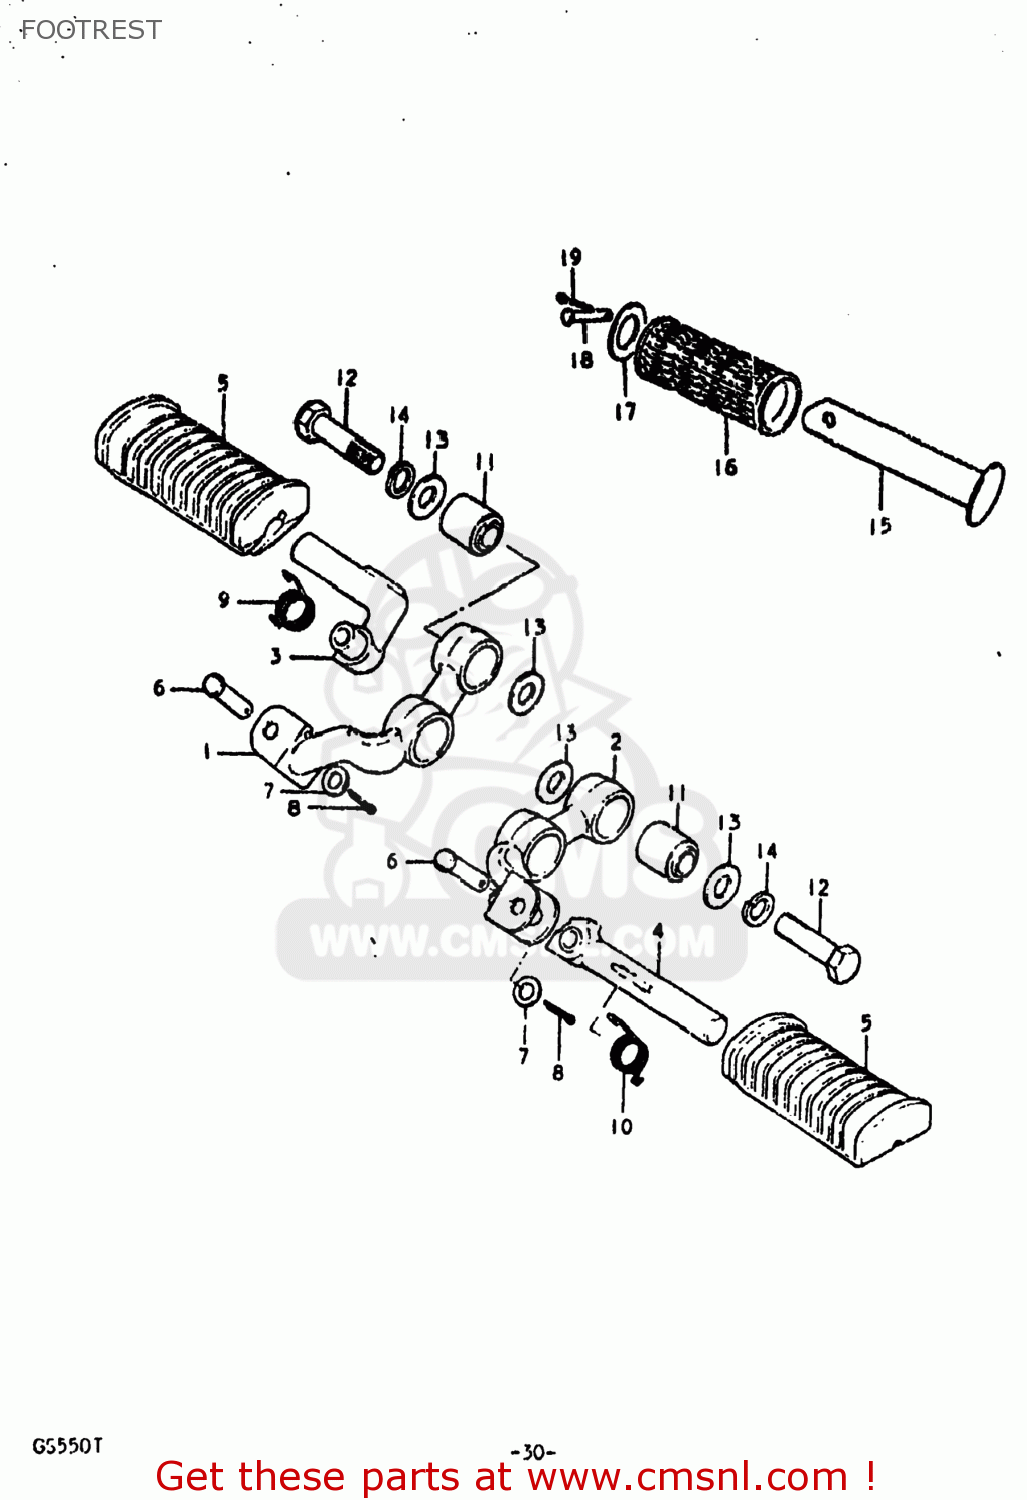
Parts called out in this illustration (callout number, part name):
1	BAR,FRONT FOOTREST,RIGHT
2	BAR,FRONT FOOTREST,LEFT
3	BAR,FRONT FOOTREST,RIGHT NO
4	BAR,FRONT FOOTREST,LEFT NO
5	RUBBER,FR FOOTREST
6	PIN
7	WASHER
8	PIN
9	SPRING
10	SPRING
11	BUSH
12	BOLT
13	WASHER (10.1X21X2.3)
14	LOCK WASHER
15	BAR,PILLION FOOTREST
16	RUBBER,REAR FOOTREST
17	WASHER (19.5X32X2)
18	PIN
19	PIN
